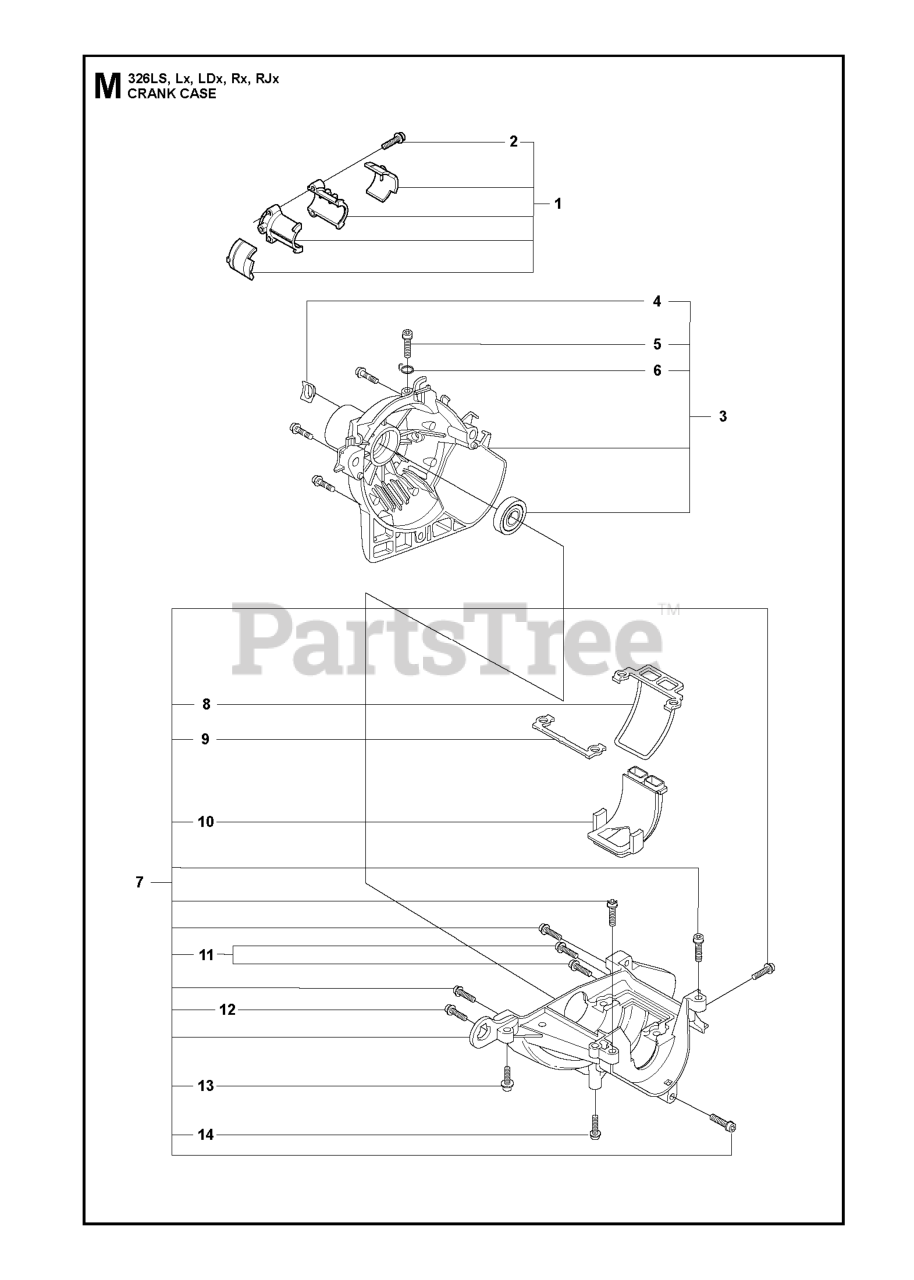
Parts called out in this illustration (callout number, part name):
1	COMPRESION SLEEVE/ISOLATOR SET
3	RP CLUTCH COVER
4	PROTECTION PLATE
5	SCREW
7	CRANKCASE
12	SCREW
